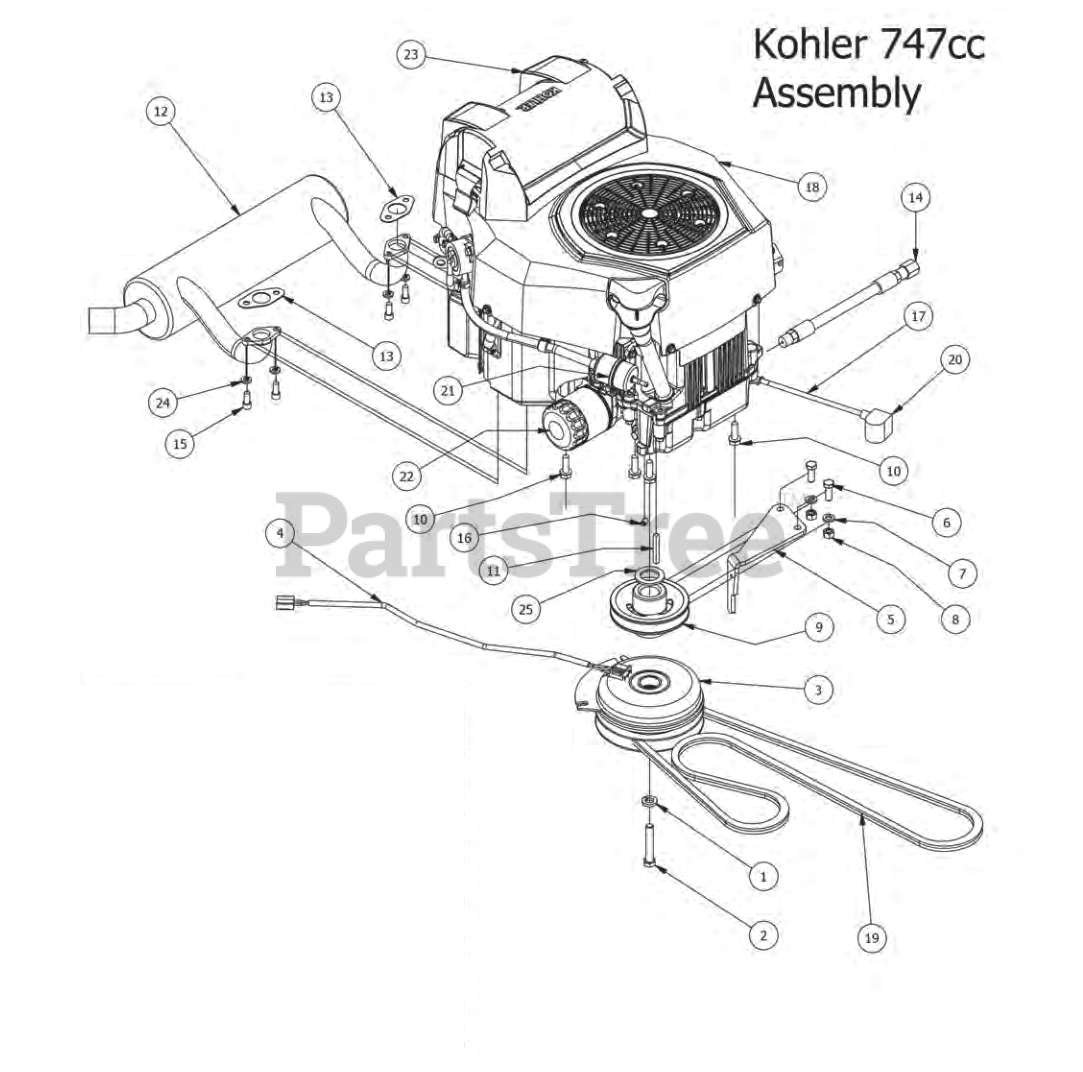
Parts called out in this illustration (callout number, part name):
1	7/16" Lock Washer
2	7/16" x 2 1/2" Hex Bolt
3	Clutch Assembly
4	Clutch Pigtail
5	PTO Engager Holder
6	3/8" x 1" Hex Bolt
7	3/8" Lock Washer
8	3/8" Hex Nut
9	4 3/4 Motor Pulley
10	3/8 x 1 1/8 bolt
11	1/4 x 2 Square key Stock
12	2014 Kohler Outlaw Muffler
13	Exhaust Gasket
14	Oil drain Valve
15	5/16-18 x 3/4 Socket C/S
16	5/16 Set Screw
17	Starter to chassis cable
18	Kohler-2014 CZT/Outlaw 747cc
20	Black Boot For ground cable
21	725 & 747 Kohler Fuel Filter
22	725 & 747 Kohler Oil Filter
23	747 Kohler Air Filter CZT/Outlaw
24	5/16" Lock Washer
25	1 1/8" Flat Spacer
